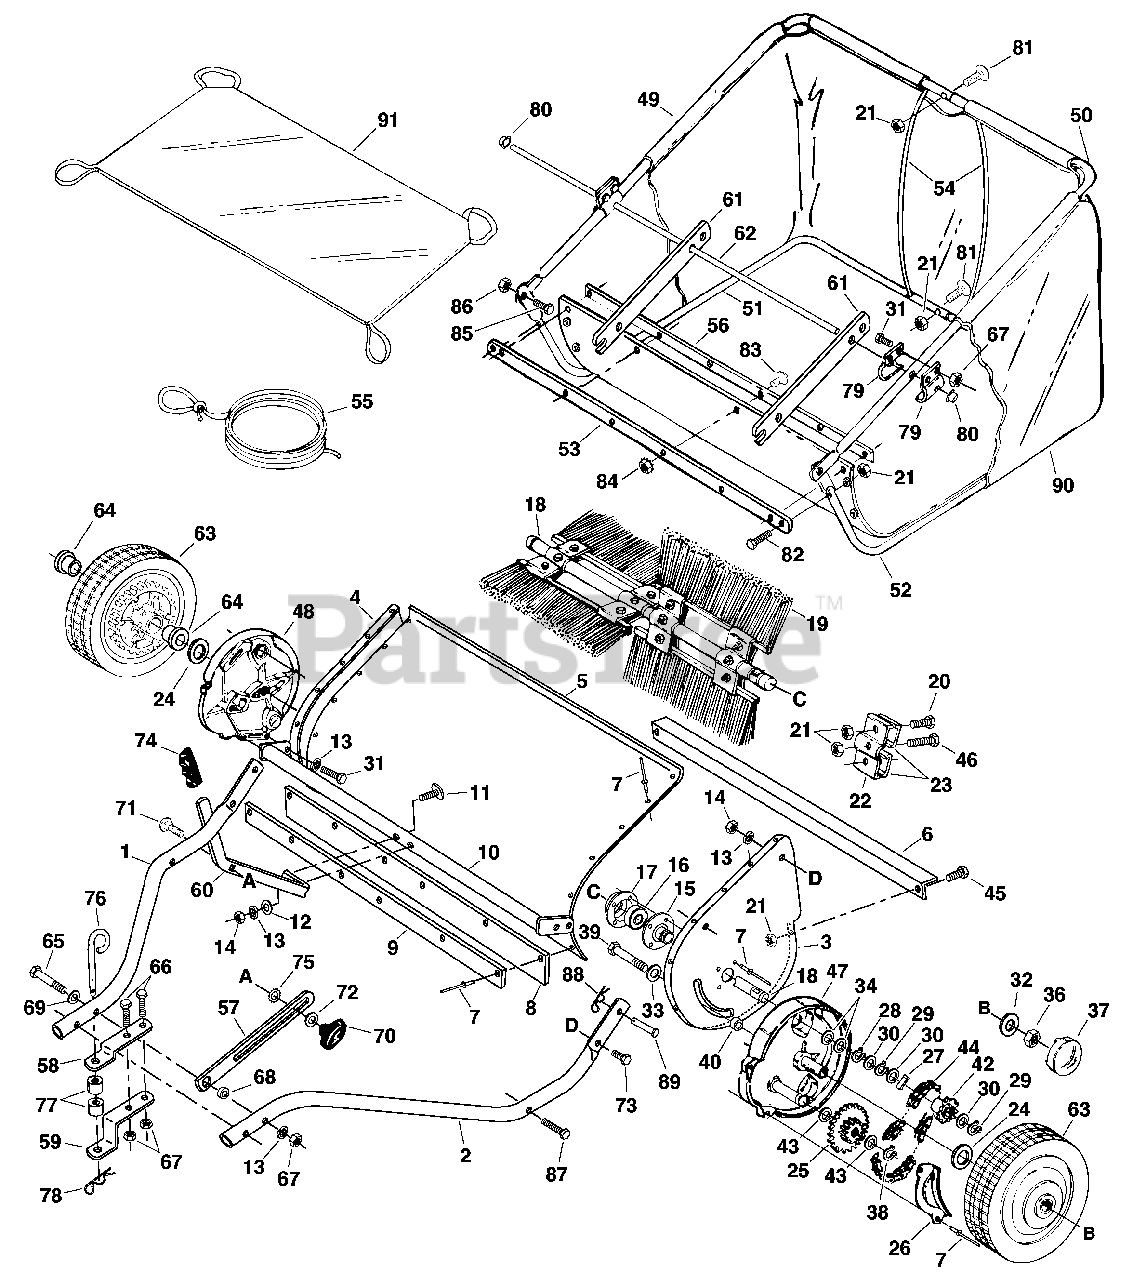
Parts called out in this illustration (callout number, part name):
1	Hitch Tube R.H. 38"
1	Hitch Tube R.H. 32"
2	Hitch Tube L.H. 38"
2	Hitch Tube L.H. 32"
3	End Plate L.H.
4	End Plate R.H.
5	Wrapper 38"
5	Wrapper 32"
6	Rear Support Brace
7	Rivet
9	Skirt & Bag Retainer 32"
9	Skirt Retainer 38"
10	Height Adjustment Ass'y. 38"
10	Height Adjustment Ass'y. 32"
11	Curved Hd. Bolt 5/16-18 x 1-5/8"
12	Washer Bowed 1" x .32" x .06"
13	Lock Washer 5/16"
14	Hex Nut 5/16-18 Thread
15	Brush Bushing Ass'y.
16	Ball Bearing
17	Bearing Retainer
18	Brush Shaft 38"
18	Brush Shaft 32"
20	Hex Bolt 1/4-20 x 3/4" (Gr. 5)
21	Hex Lock Nut 1/4-20 Thread
22	Brush Retainer (Double)
23	Brush Retainer (Single)
24	Flat Washer 1-1/4" x .78 I.D.
25	Gear Sprocket Sub Ass'y.
26	Dust Cover
28	Retaining Ring 3/4"
29	Retaining Ring .594" I.D.
30	Shim Washer 1-1/8" x .594" x .025"
31	Hex Bolt 5/16-18 x 3/4"
32	Flat Washer 1-1/2" x .375" x .062"
33	Washer 3/8" Standard
34	Flat Washer .78" x 1.25" x .06"
36	Hex Lock Nut 3/8-24 Thread
38	Retaining Ring 1/2"
39	Hex Bolt 3/8-24 x 3-1/4" (Gr. 5)
40	Spacer 13/32" x 5/8" x 3/16"
42	Ratchet Sprocket L.H.
43	Washer 1/2" x 1" x .02"
44	Roller Chain 3/8" x 1/2-40
45	Hex Bolt, 1/4-20 x 1/2"
46	Hex Bolt 1/4-20 x 1"
47	Wheel Drive Housing Ass'y. L.H.
48	Wheel Drive Housing Ass'y. R.H.
49	Upper Hopper Tube L.H. 32"
49	Upper Hopper Tube R.H. 38"
50	Upper Hopper Tube L.H. 38"
50	Upper Hopper Tube R.H. 32"
51	Lower Hopper Tube R.H. 38"
52	Lower Hopper Tube L.H. 32"
52	Lower Hopper Tube L.H. 38"
53	Bag Frame Strap 32"
53	Bag Frame Strap 38"
54	Hopper Support Rod
55	Hopper Rope
56	Skirt & Bag Retainer 38"
56	Skirt & Bag Retainer 32"
57	Height Adjustment Strap
58	Hitch Bracket
59	Hitch Bracket
60	Height Adjustment Handle
62	Hopper Bag Pivot Rod 32"
62	Hopper Bag Pivot Rod 38"
63	Wheel Ass'y. Complete
64	Wheel Bearing
65	Hex Bolt 5/16-18 x 3"
66	Hex Bolt 5/16-18 x 2-1/4"
67	Hex Lock Nut 5/16-18 Thread
68	Spacer Bushing
69	Flat Washer 1/4" Standard
70	Wing Knob 5/16-18 Thread
71	Carriage Bolt 5/16-18 x 3/4"
72	Washer 5/16" Standard
73	Hex Bolt 5/16-18 x 1"
74	Rubber Grip
75	Tooth Lock Washer 5/16"
77	Hitch Adjustment Tube
78	Hairpin Cotter 1/8" #4
79	Hopper Mount Clamp
80	Palnut 3/8"
81	Curved Head Bolt 1/4-20 x 1"
82	Hex Bolt 1/4-20 x 1-1/4"
83	Slotted Truss Head Screw #10-32 x 5/8"
84	Hex Lock Nut #10-32 Thread
85	Hex Bolt 3/8-16 x 3/4" (Gr. 5)
86	Hex Lock Nut 3/8-16 Thread
87	Hex Bolt 5/16-18 x 1-3/4"
88	Hairpin Cotter 3/32" #3
90	Hopper Bag 38"
90	Hopper Bag 32"
91	Wind Screen 32"
91	Wind Screen 38"
